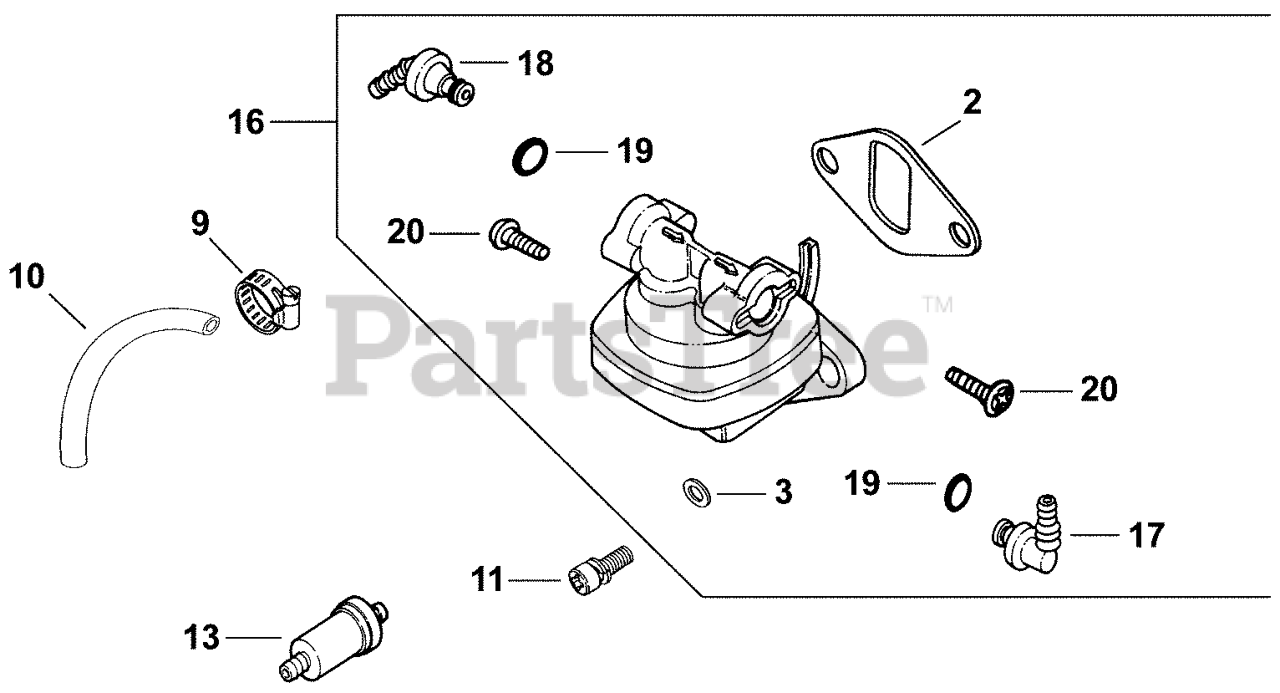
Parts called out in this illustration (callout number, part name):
2	GASKET, FUEL PUMP - USE 25 041 09-S
3	WASHER - USE X-25-63-S
9	CLAMP, HOSE 1/2" USE 25 237 14-S
10	LINE - DISCONTINUED
11	SCREW, SEMS 1/4-20X3/4"
16	PUMP - USE 47 559 04-S
17	FITTING - USE 25 294 01-S
18	FITTING - USE 25 294 02-S
19	O-RING FITTING - USE 25 153 01-S
20	SCREW - USE 25 086 35-S
